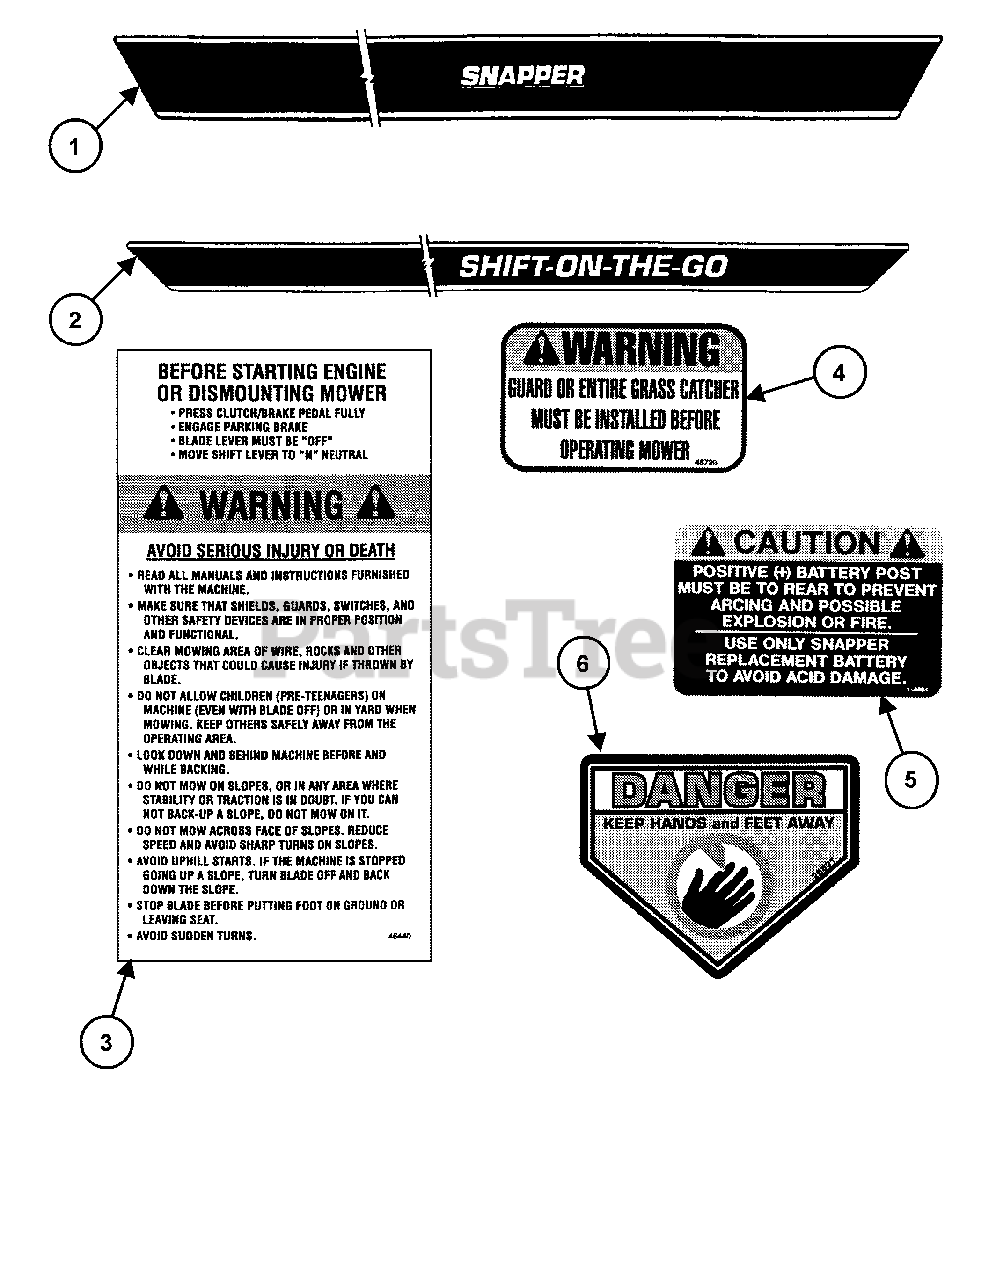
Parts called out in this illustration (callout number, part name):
1	DECAL, Banner (Blue)
2	DECAL, Bumper Stripe (Blue)
3	DECAL, Warning, Safety Instruction
4	DECAL, Chute/Deflector
5	DECAL, Caution, Battery
6	DECAL, Danger (Heavy Adhesive)
